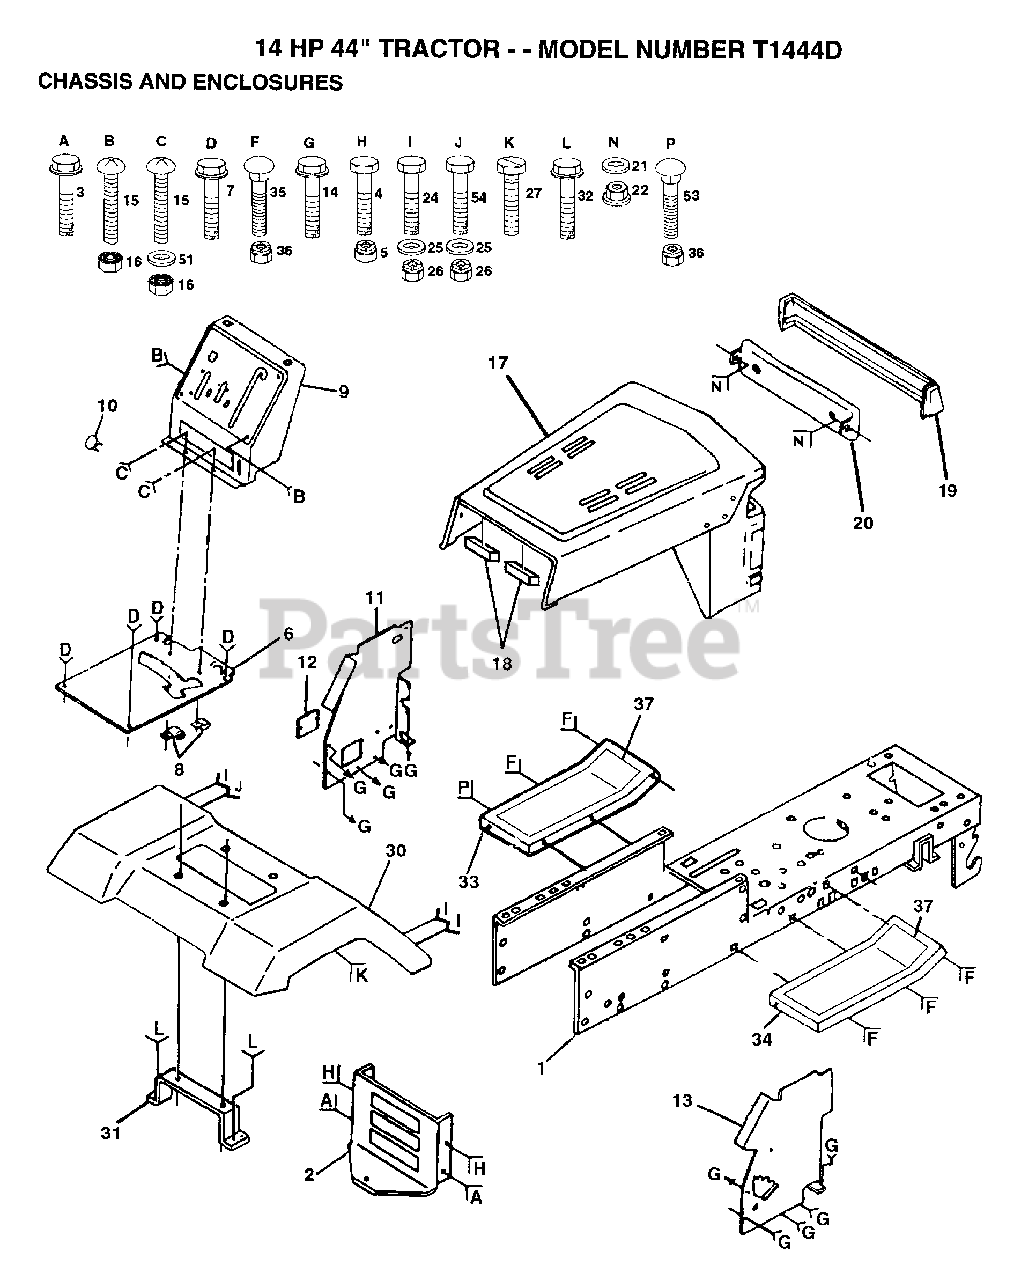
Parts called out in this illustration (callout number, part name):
1	CHASSIS
3	SCREW
7	SCREW LT
8	CLIP T
9	DASH.SLKSCR.1PC
10	PLUG BUTTON T
11	PANEL DASH LH
12	COVER ACCESS
14	SCREW LT
16	NUT
17	HOOD/GRILL ASM
21	WASHER PM
22	PAL NUT LT
25	WASHER
27	SCREW LT
31	BRKT FENDER
32	SCREW
35	BOLT
37	FOOTREST PAD
51	WASHER
